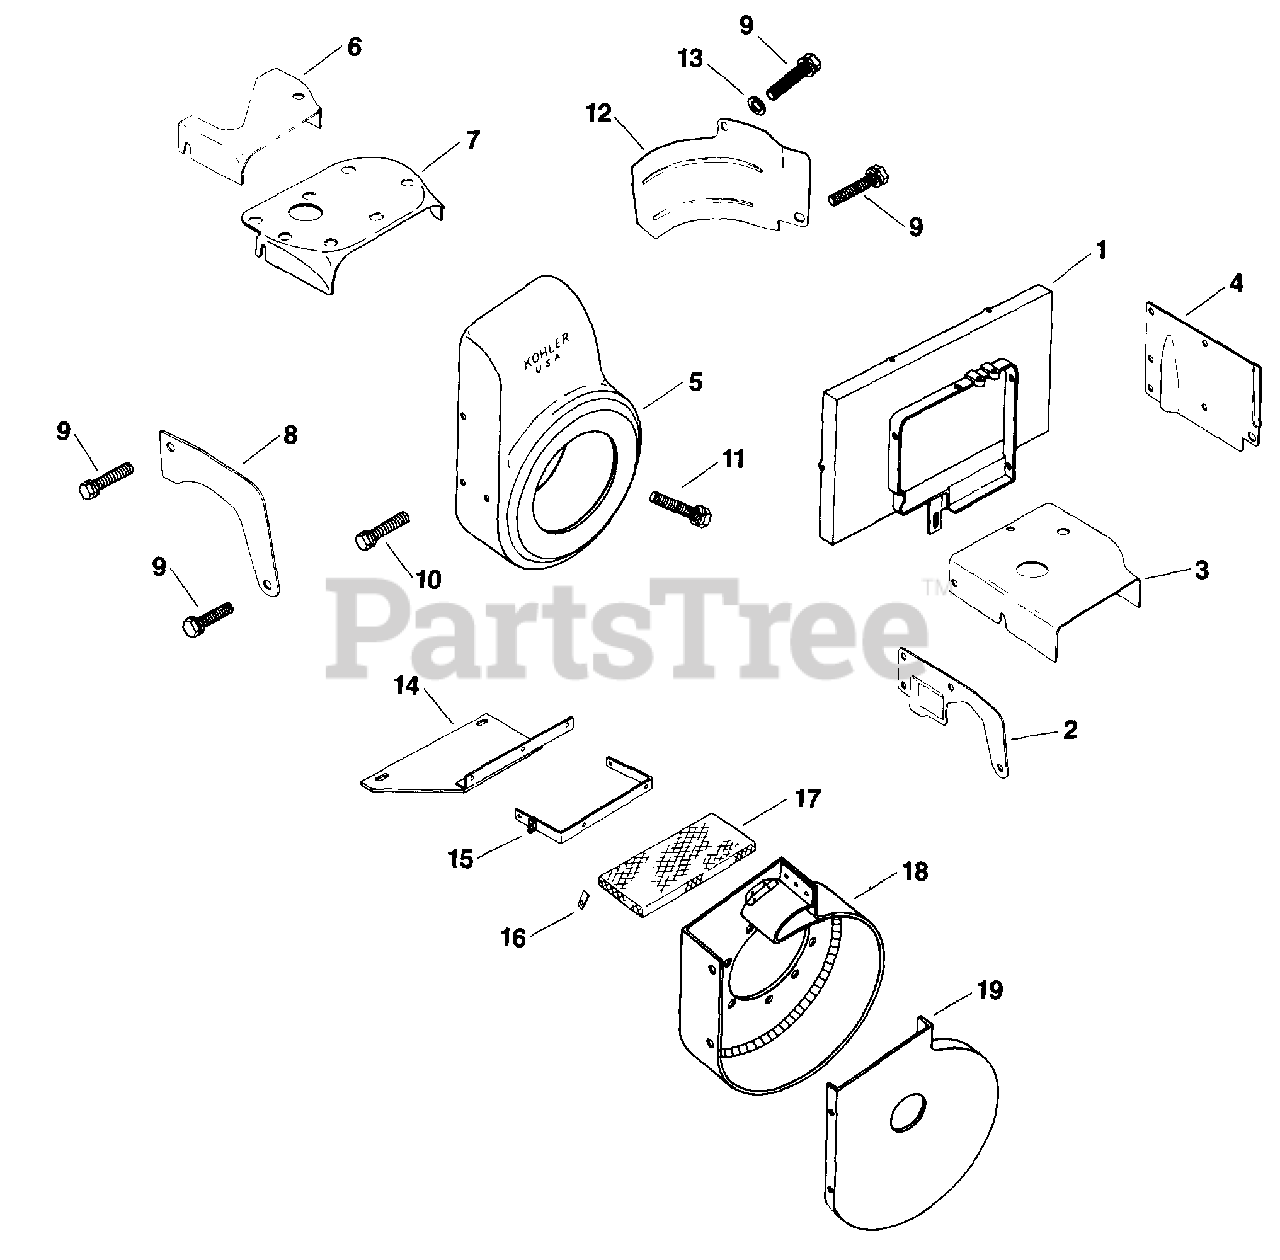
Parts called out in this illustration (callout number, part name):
5	KIT, HOUSING
7	BAFFLE, HEAD
9	SCREW - DISCONTINUED
10	SCREW, SEMS 1/4-20-1/2"
12	BAFFLE, CYLINDER
13	WASHER, FLAT 1/4" (O.D. 5/8")
